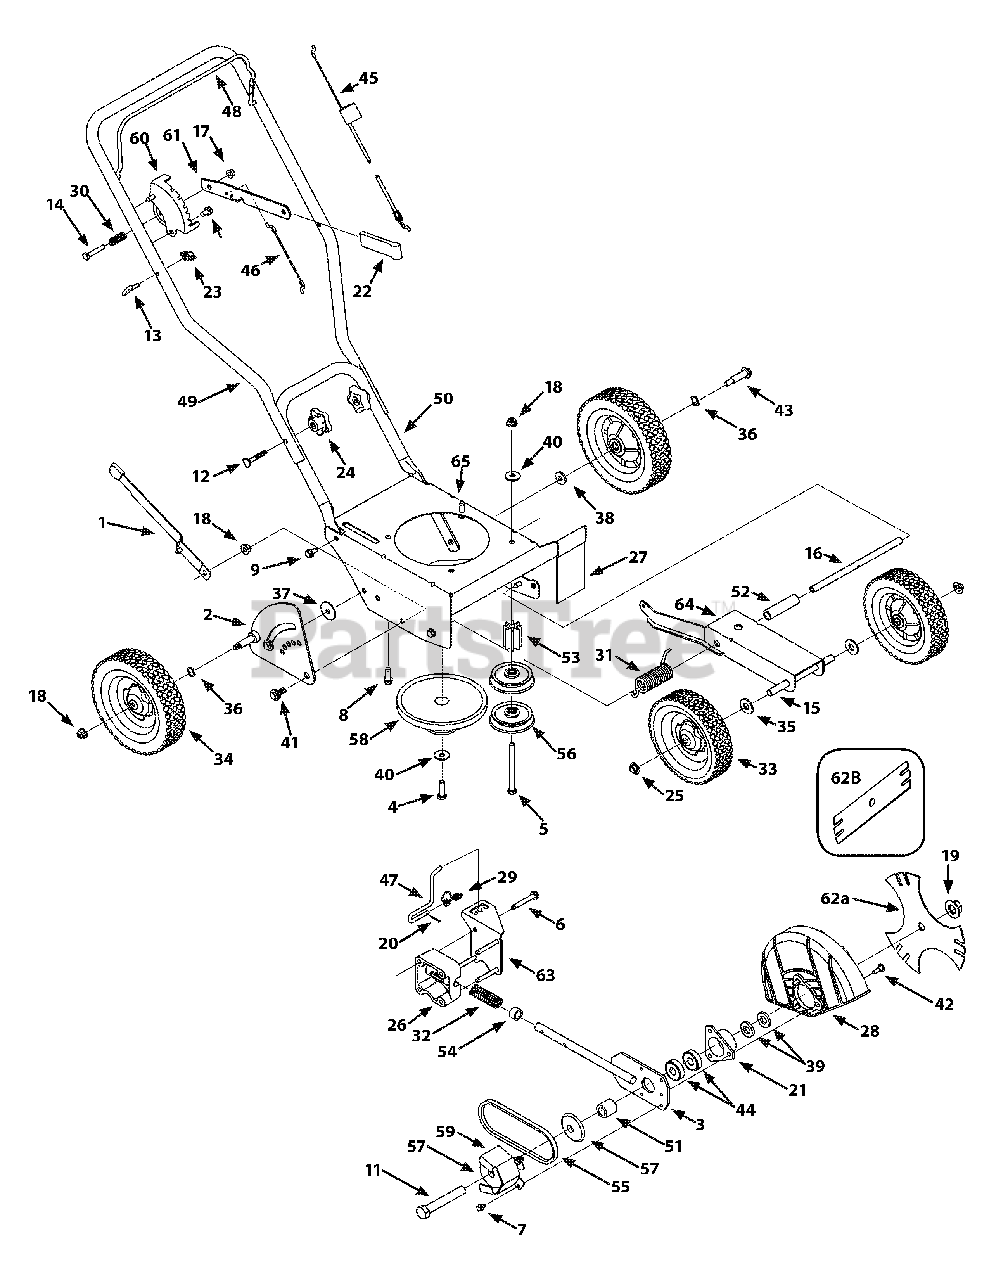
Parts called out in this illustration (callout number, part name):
1	Curb Height Adjustment Lever
2	Curb Height Adjuster Plate
3	Blade Plate Assembly
4	Screw 3/8-24
5	Screw 3/8-16
6	Hex Screw, 5/16-18
7	Self-Tapping Screw, 1/4-20
8	Screw, 3/8-16
9	Hex Screw, 5/16-12
10	Hex Screw, 5/16-18
11	Hex Screw, 5/8-18
12	Carriage Bolt, 5/16-18
13	Rope Guide
14	Hex Screw, 5/16-18
15	Axle Shaft .50 x 6.65
16	Frame Spacer.50 x 9.25
17	Lock Flange Nut, 5/16-18
18	Flange Nut, 3/8-16
19	Flange Nut, 5/8-18
20	Clevis Pin, 3/32 x .625
21	Bearing Cup
24	Star Knob
25	Push Cap 1/2'' Rod
26	Bearing Block
27	Debris Guard
28	Blade Guard
29	Double Torsion Spring
30	Compression Spring
31	Torsion Spring
32	Compression Spring
33	Front Wheel 7x 1.75 T-Tread
34	Rear Wheel 8 x 1.75 T-Tread
35	Flat Washer, 1/2 x 1.25 x .10
36	Wave Washer .531 x .781 x .013
37	Flat Washer, .385 x 1.5 x .075
38	Flat Washer, .385 x 1.0 x .135
39	Flat Washer, .635 x 1.24 x .181
40	Bell Washer, .396 x 1.140
41	Shoulder Screw, 3/8-16
42	Shoulder Screw
43	Shoulder Screw, 3/8-16
44	Bearing, .625 ID x 1.57 OD
45	Control Cable
46	Wheel Adjustment Cable
47	Blade Adjustment Rod
51	Spacer, .63 x 1.12 x 1.06
53	Pulley Mount Spacer
54	Spacer, .64 x .88 x .50
55	Belt
56	Flat Idler Pulley, 2.5 OD
57	Sheave
58	Combination Flywheel Pulley
